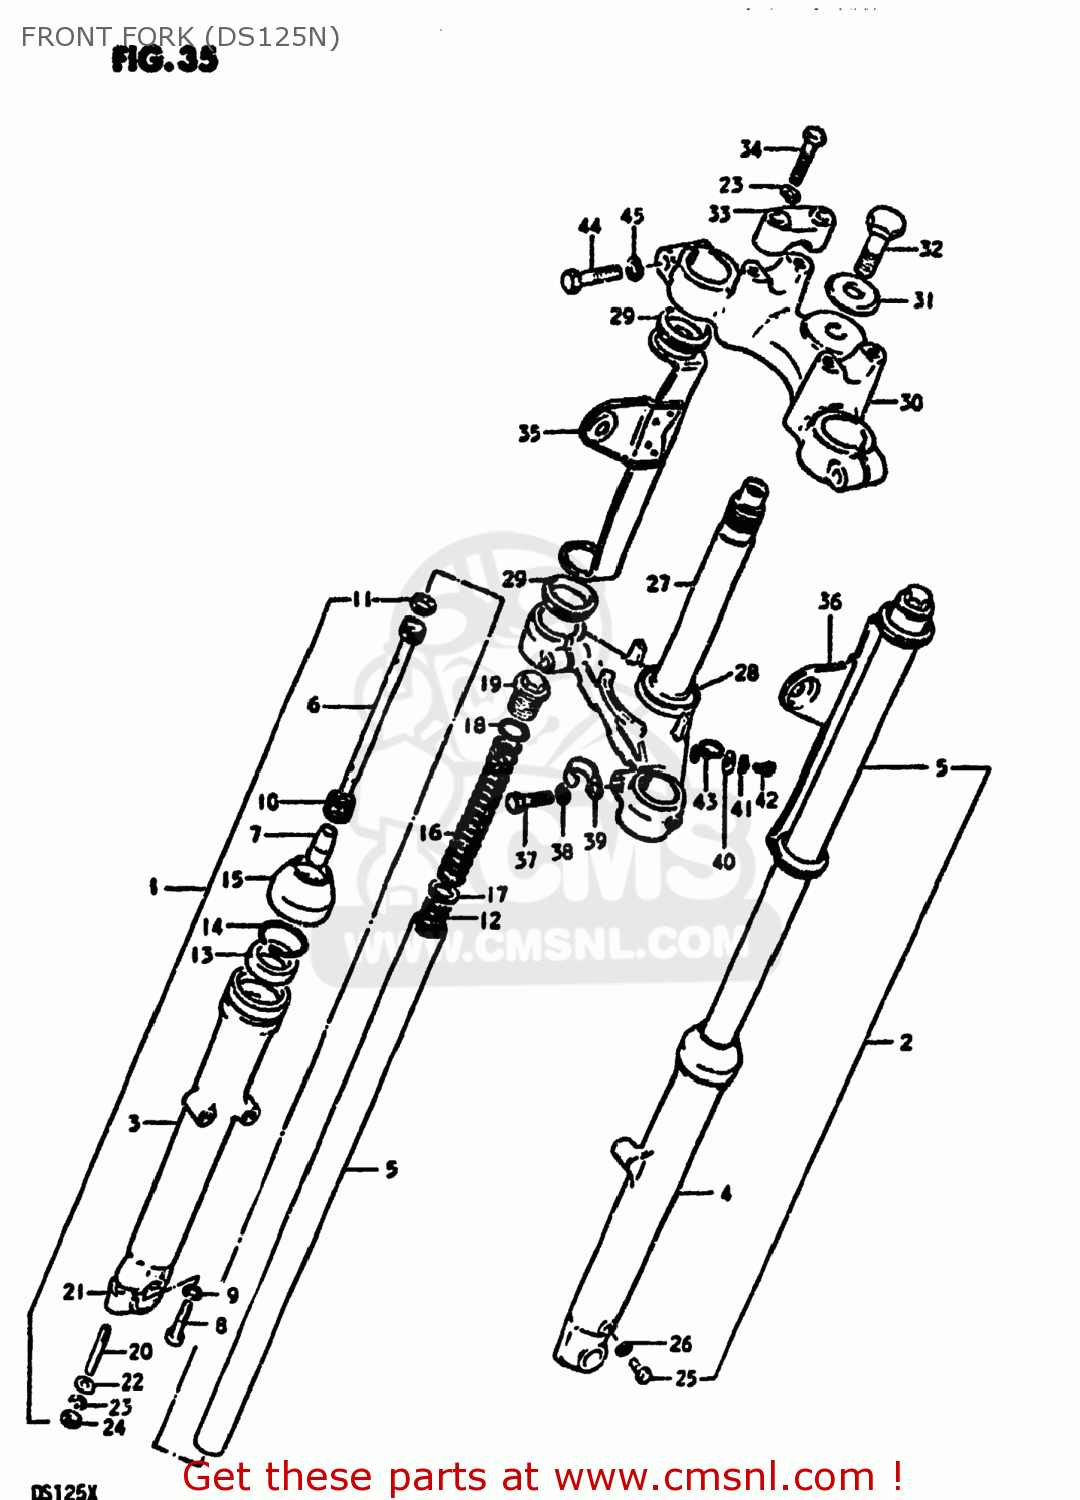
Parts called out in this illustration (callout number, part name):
1	DAMPER ASSEMBLY,RIGHT
2	DAMPER ASSEMBLY,LEFT
3	TUBE,OUTER,R
4	TUBE,OUTER,L
5	TUBE,INNER
6	CYLINDER,FRONT FORK
7	PIECE,OIL LOCK
8	BOLT
9	GASKET (NAS)
10	SPRING,FORK REBOUND
11	RING
12	SPRING,FRONT FORK
13	OIL SEAL,FRONT FORK
14	CIRCLIP,FORK OIL SEAL
15	DUST SEAL,FRONT FORK
16	SPRING,FRONT FORK
17	SEAT,SPRING
18	O RING
19	BOLT
20	STUD 8X25
21	HOLDER,AXLE(BLACK)
22	WASHER
23	LOCK WASHER
24	NUT
25	BOLT(6X8)
26	GASKET,DRAIN,PLUG (NAS)
27	STEM,STEERING
28	RACE,STEERING OUTER LWR
29	CUSHION
30	HEAD,STEERING STEM(BLACK)
31	WASHER(10.5X30X2.3)
32	BOLT,STEERING STEM HEAD
33	HOLDER,HANDLEBAR
34	BOLT
35	BRACKET,HEADLAMP,RIGHT
36	BRACKET,HEADLAMP,LEFT
37	BOLT
38	WASHER,LOCK 12
39	CLIP
40	WASHER
41	LOCK WASHER
42	SCREW 6X12
43	CLIP
44	BOLT
45	LOCK WASHER
